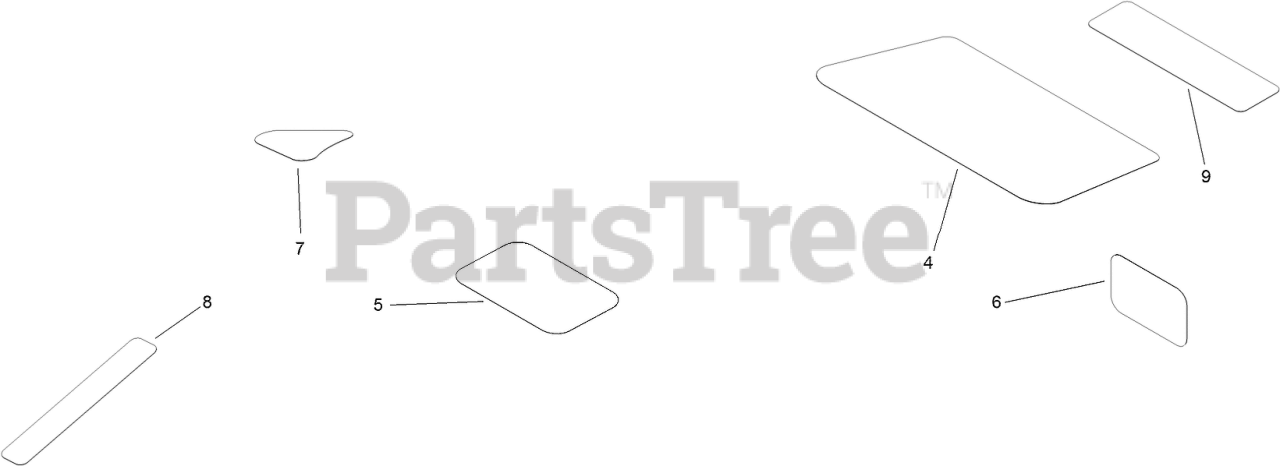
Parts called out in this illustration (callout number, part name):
4	DECAL-ENGINE
6	PLACARD-INTAKE
7	DECAL-DRAIN, OIL
8	DECAL-SHUTDOWN
9	DECAL-BUCKET
